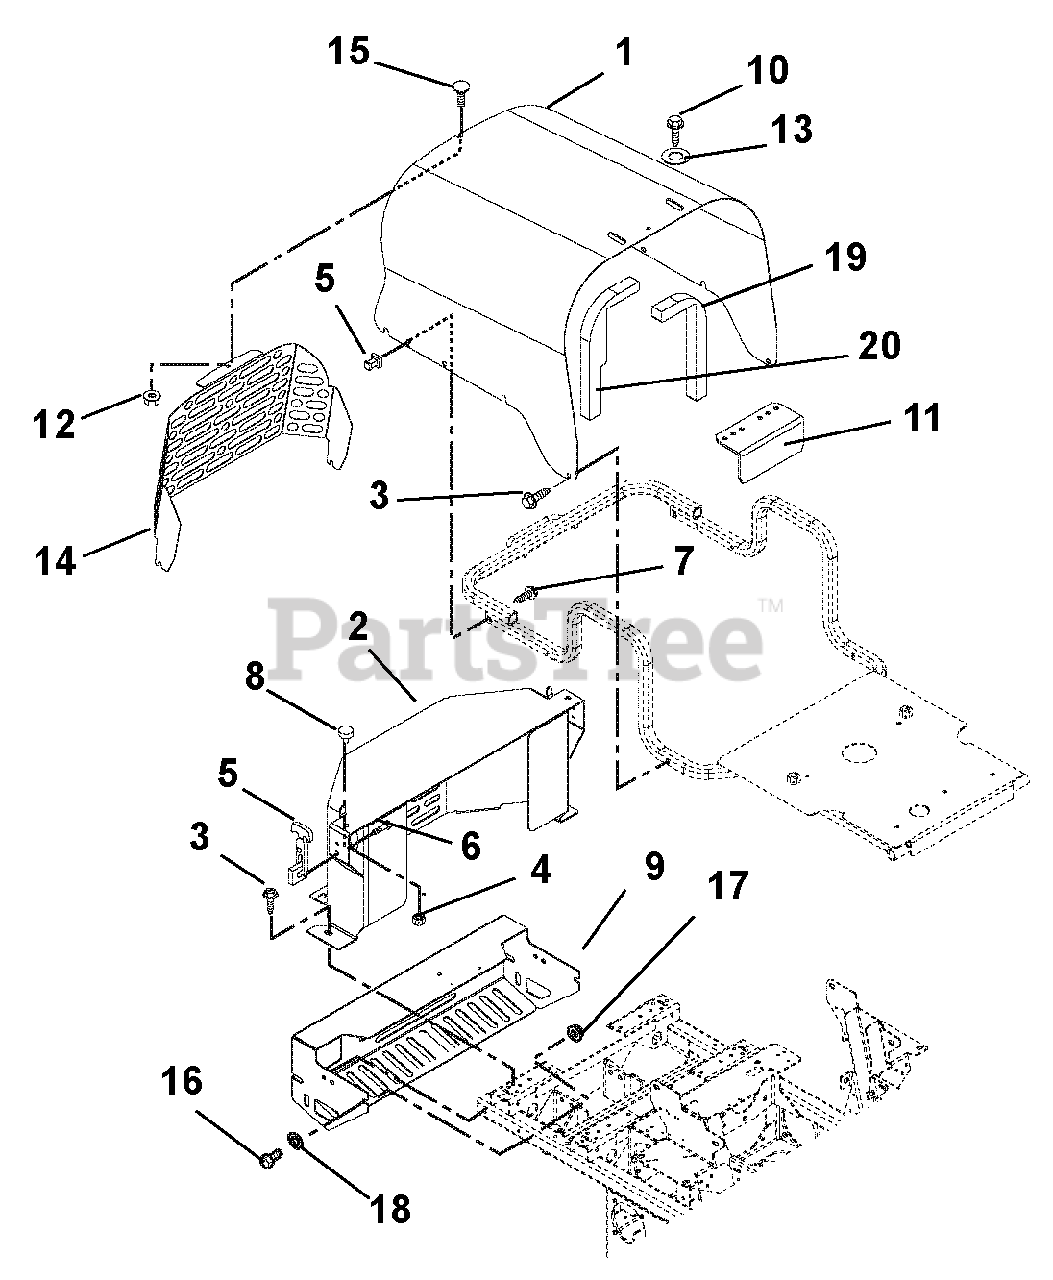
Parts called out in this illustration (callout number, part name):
2	Diesel Belt Guard, Weldment
3	Screw, Tapping .38-16 x .75 Hex Washer Head
4	Nut, Spin Lock, Flange .312-18
5	Latch, Rubber
6	Screw, Machine 10-24 x .50 Hex Washer Head
7	Screw, Machine 10-24 x 1.50 Hex Washer Head
8	Bumper, Rubber
9	Bumper, Weldment, PM200 CE
10	Screw, Tapping Hex Washer Head .25-20 x .50
11	Guard, Radiator Cap
12	Nut, Locking Top Flange .25-20
13	Washer, Flat Steel .281 x .62 x .065
14	Guard, Hood
15	Bolt, Round Head Square Neck .25-20 x .50 Grade 5
16	Bolt, Hex .38-16 x 2.75 Grade 5
17	Nut, Locking Top Flange .38-16
18	Washer, Flat Steel .406 x .812 x .065
19	Dam, Left Side Foam Air
20	Dam, Right Side Foam Air
